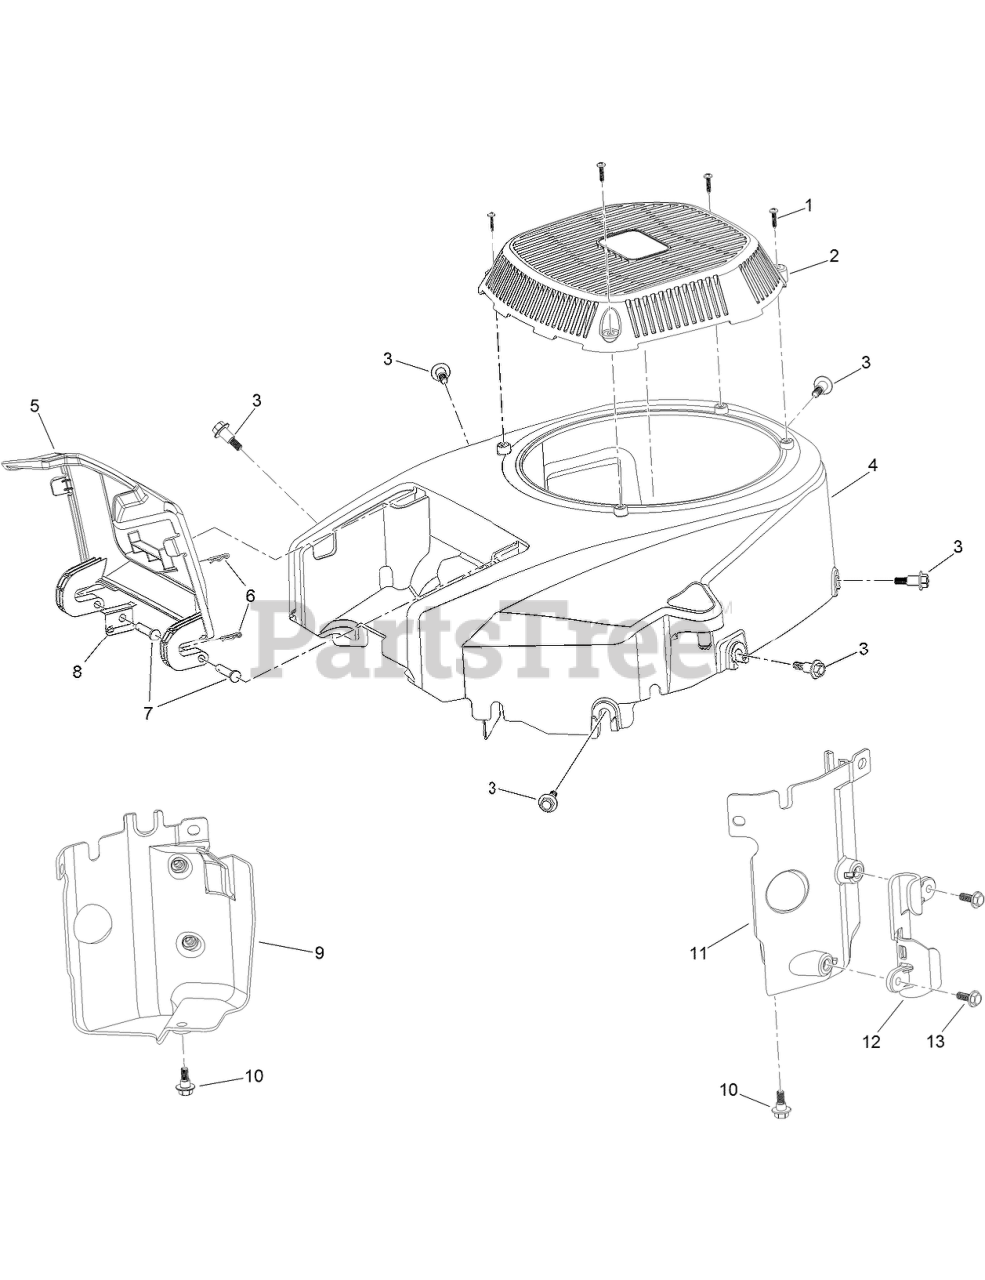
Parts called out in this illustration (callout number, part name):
1	SCREW-PLASTIC, PPH
2	COVER-FAN
3	SCREW-SHOULDER, HWH
4	SHROUD-ENGINE
5	DOOR-FILTER, AIR
6	PIN-HAIR
8	PLATE-SPRING
9	BAFFLE-AIR, LEFT
10	SCREW-SHOULDER, HHF
11	BAFFLE-AIR, RIGHT
12	CLEAT-HOSE
13	SCREW-HHF
